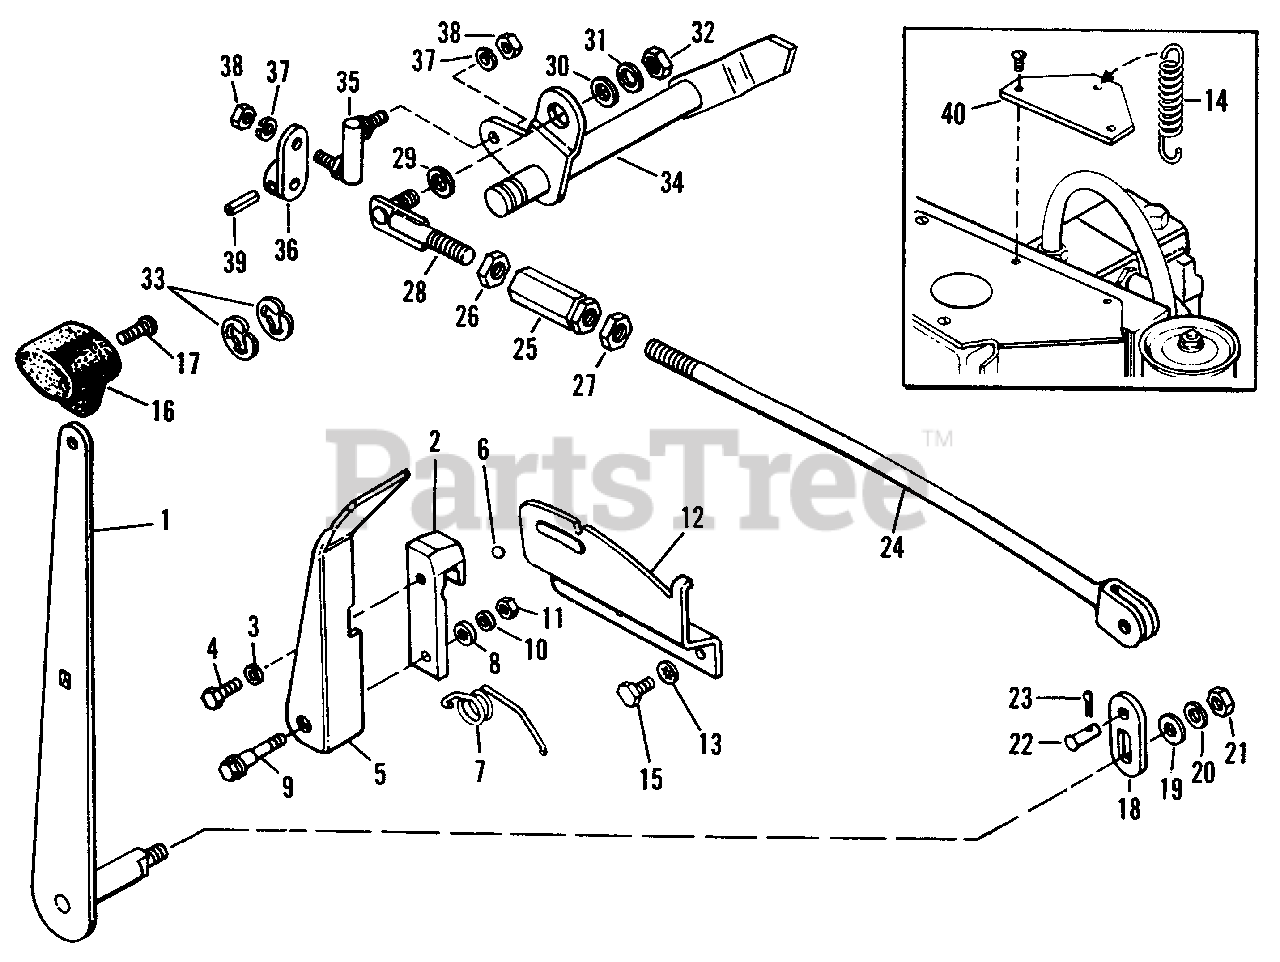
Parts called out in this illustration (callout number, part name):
1	Lever Assembly
2	Stop Clamp
3	Lockwasher, 1/4" Std.
4	Hex Capscrew, 1/4"-20 N.C. x 1/2"
6	Shift Ball Handle, 5/16"
9	Shoulder Bolt
10	Plain Washer, 1/4"
11	Full Hex Lock Nut, 1/4"-20
13	Shakeproof Lockwasher, 5/16"
15	Special Screw
17	Screw, Thd. Form, 1/4"-20 x 7/8"
19	Plain Washer, 3/8"
20	Lockwasher, 3/8"
21	Full Hex Nut, 3/8"-16
23	Cotter Pin, 3/32" x 3/4"
24	Rod Assembly Control, Front
25	Turn Buckle
26	Full Hex Nut, 7/16"-14 L.H.
27	Full Hex Nut, 7/16"-14 R.H.
28	Rod Assy., Rear Control
30	Plain Washer, 5/16"
31	Lockwasher, 5/16"
32	Full Hex Nut, 3/8"-16
33	"E" Ring
34	Shaft Assembly Control
35	Ball Joint, Double End
36	Link Assembly Control
37	Lockwasher, 5/16"
38	Full Hex Nut, 5/16"-24
39	Roll Pin, 1/4" x 1-1/4"
40	Spring Clip
